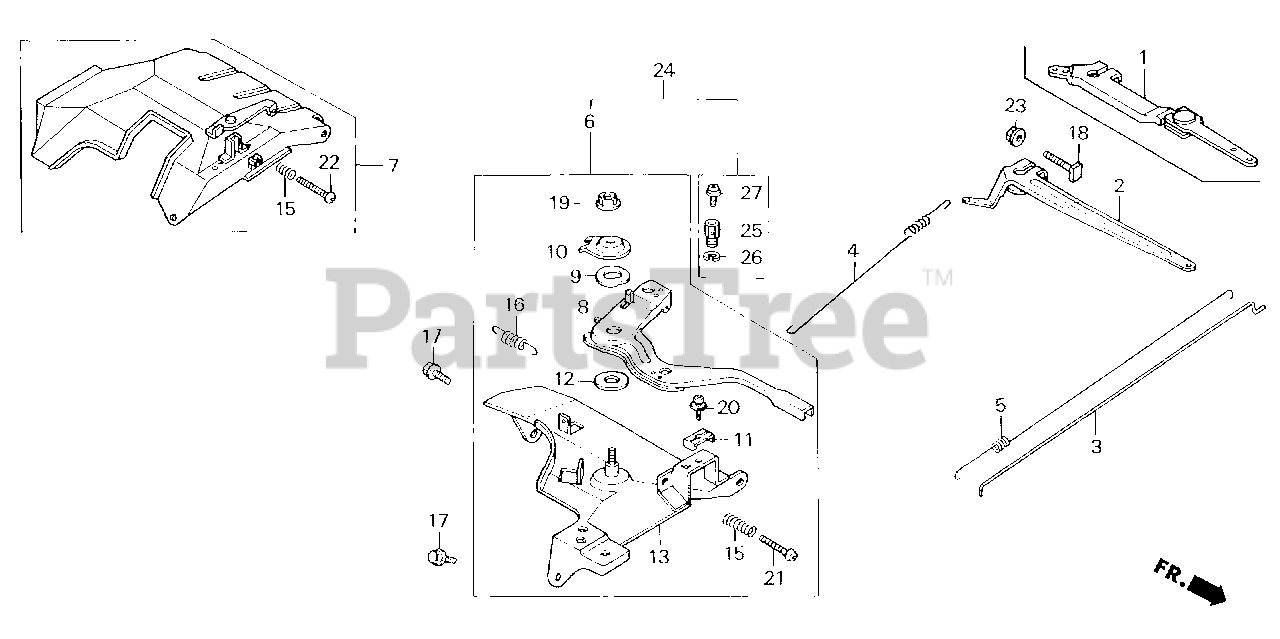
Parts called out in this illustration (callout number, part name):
1	ARM, GOVERNOR
3	ROD, GOVERNOR
4	SPRING, GOVERNOR
7	CONTROL ASSY.
15	SPRING, CONTROL ADJUSTING
17	BOLT, FLANGE (6X12) (CT200)
18	BOLT, GOVERNOR ARM
22	SCREW, PAN (5X35)
23	NUT, FLANGE (6MM)
